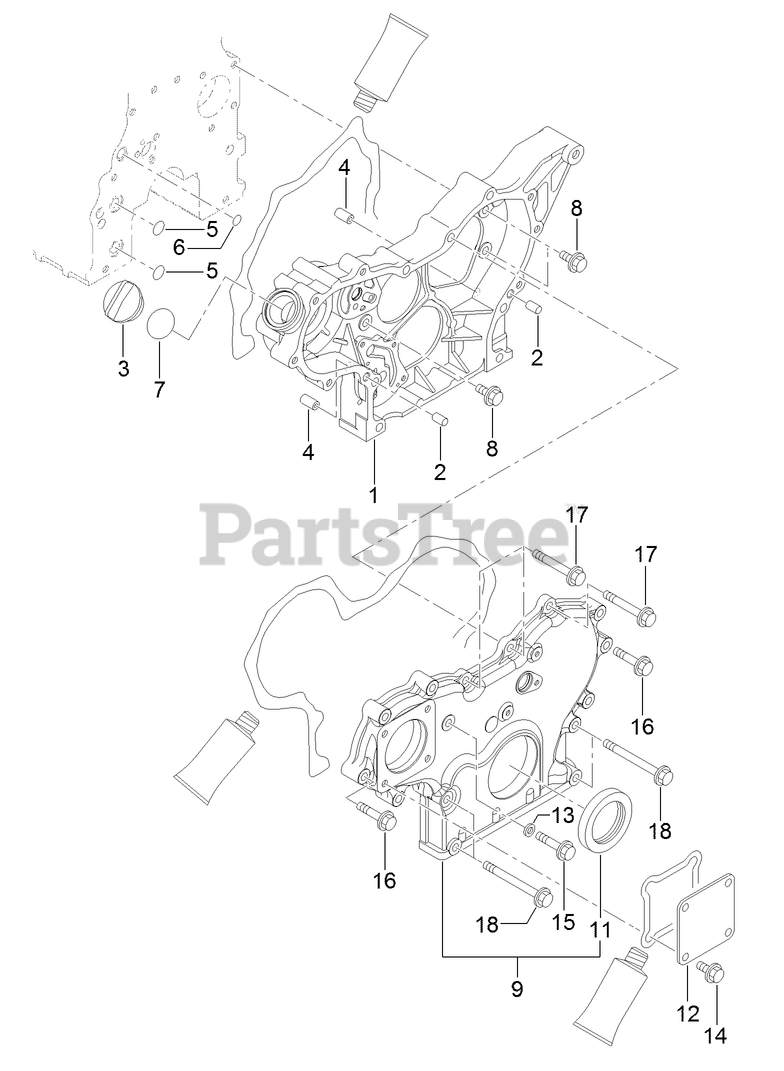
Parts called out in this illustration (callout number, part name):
1	CASE-GEAR
3	COVER-FILLER
5	O-RING
6	O-RING
7	O-RING
8	BOLT
9	GEARCASE COVER ASM
11	SEAL-OIL
13	WASHER-SEAL
14	BOLT
